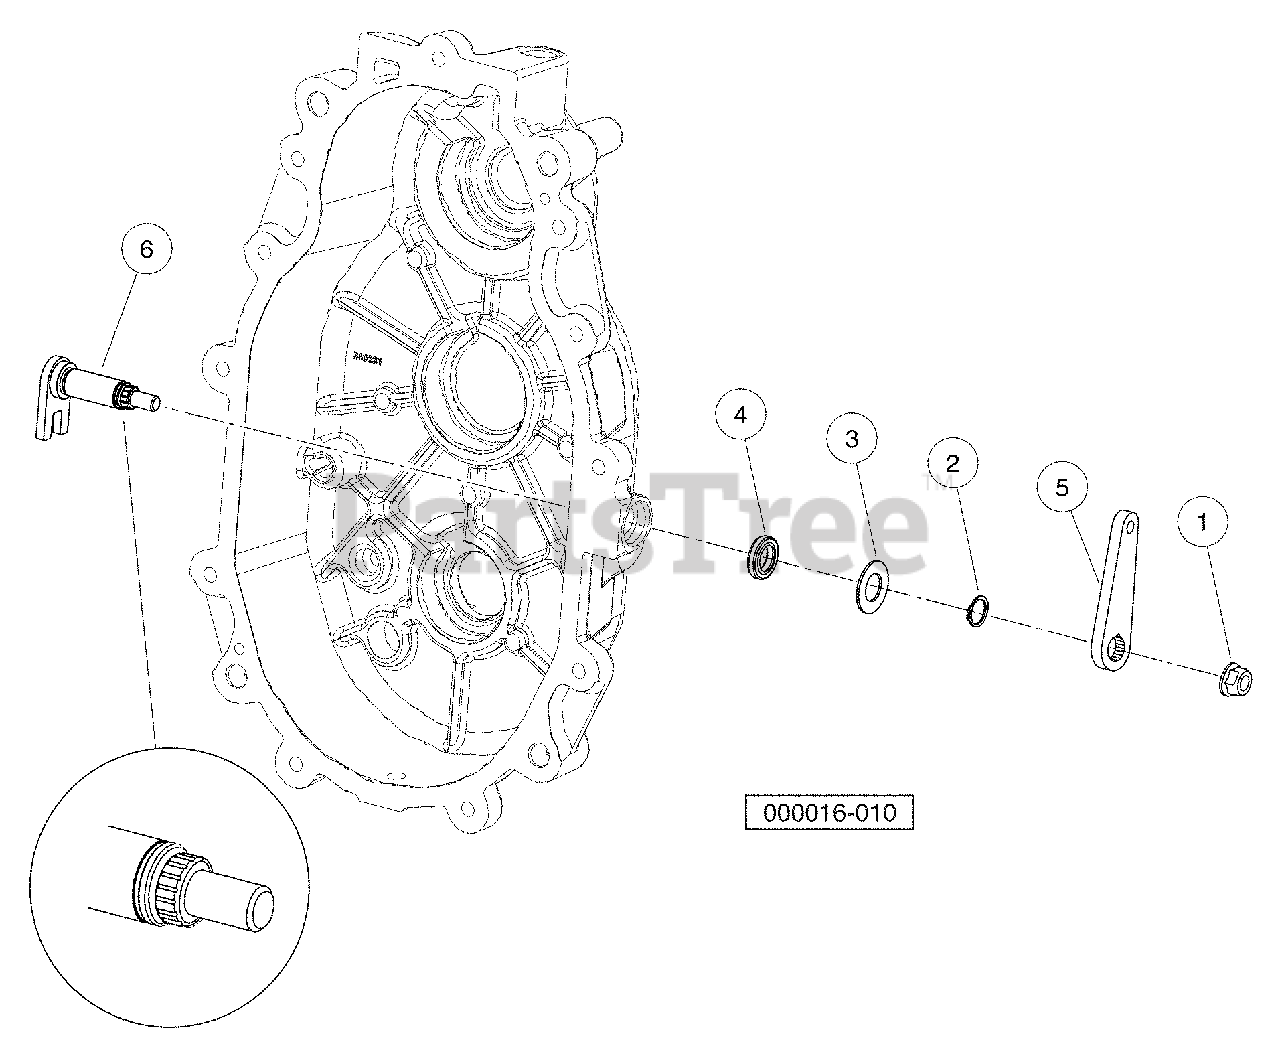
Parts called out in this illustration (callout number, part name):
1	Nut, Lock Hex, Nylon, 5/16-24
2	Ring, Retaining, External 9/16
3	Washer, Flat, .58 X 1.08 X .05
4	Seal, Dul Lip, .88 X .56 X .19
5	Bellcrank, Alum
6	Shaft, Shift
